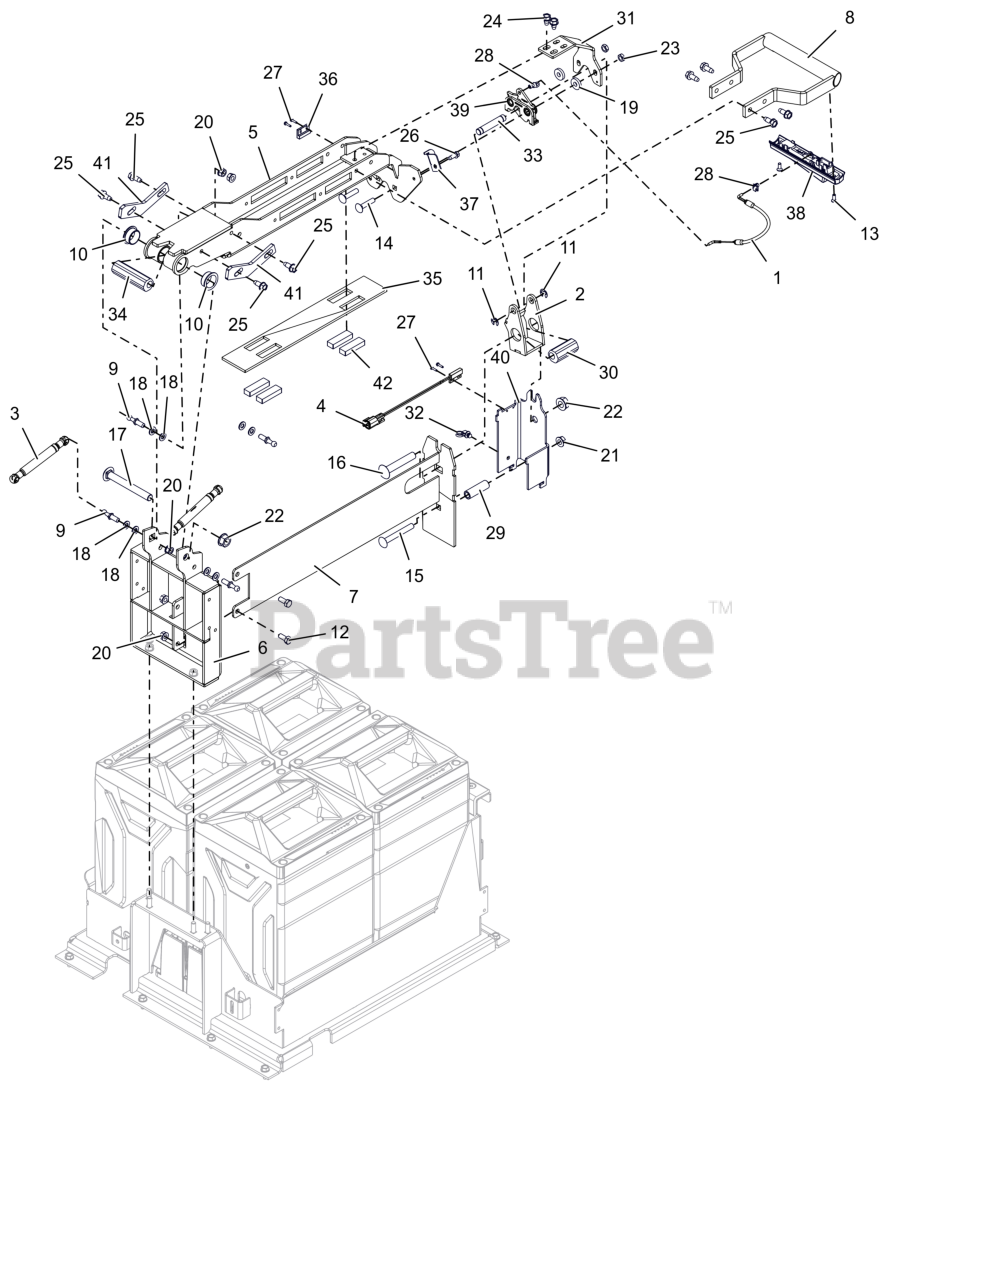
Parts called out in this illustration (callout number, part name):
1	CABLE, HOOD RELEASE
2	WLDMT, ECCENTRIC
3	DAMPER, GAS
4	SWITCH, MAGNETIC
5	WLDMT- HOLDOWN MAIN
6	WLDMT- PIVOT BATTERY HOLDDOWN
7	WLDMT- ECCENTRIC MTG
8	WLDMT, HANDLE (RED)
9	STUD-BALL-THREADED
10	BSHG-FLG 1.0X1.125X.50X1.375 R
11	RG-RTNG-EXT .438X.035
12	BLT,HEX .31-18X.75 G5 ZCC
13	SCR, FLCSKH M5-0.8X14 GR10.9 ROHS
14	BLT,RHSN .31-18X1.50 G5 ZCC
15	BTL,RHSSN .375-16 X 3 G5 ZCC
16	BTL,RHSSN .500-13 X 3 G5 ZCC
17	BTL,RHSSN .500-13X 4.0 G5 ZCC
18	WSHR,FLT .323X.625X.062 ZCC
19	WSHR, FLT .328X.870X.179 ZCC
20	NUT,LK-CTR-FLG .31-18 GF ZCC
21	NUT-LK-CTR-FLG .375-16 GF ZCC
22	NUT-LK-CTR-FLG .500-13 GG ZCC
23	NUT-LK-CTR-JAM .312-18 GB ZCC
24	SCR,TAP .312-18X.50 HWH TR ZCC
25	SCR,TAP .312-18X.75 HWH TR ZCC
26	SCR,TAP .25-20X.625 HWH ZCC
27	SCR-TAP #4-40X.50 HWH ZCC
28	CLIP, RETAINER
29	SPCR, LATCH BRKT (BLACK)
30	ECCENTRIC, HOOD LATCH
31	BRKT, LATCH MTG (RED)
32	CABLE TIE W/ TREE (.25 HOLE)
33	ROD, LATCHING
34	ECCENTRIC, HOOD LATCH-FRONT
35	PAD, RUBBER
36	SWITCH, MAGNET (NO WIRE)
37	RETAINER, CABLE (BLACK)
38	HANDLE, SQUEEZE ACTUATOR
39	LATCH, PUSH TO CLOSE
40	BRKT- ECCENTRIC MTG
41	STOP, HOOD (BLACK)
42	PAD, RUBBER
